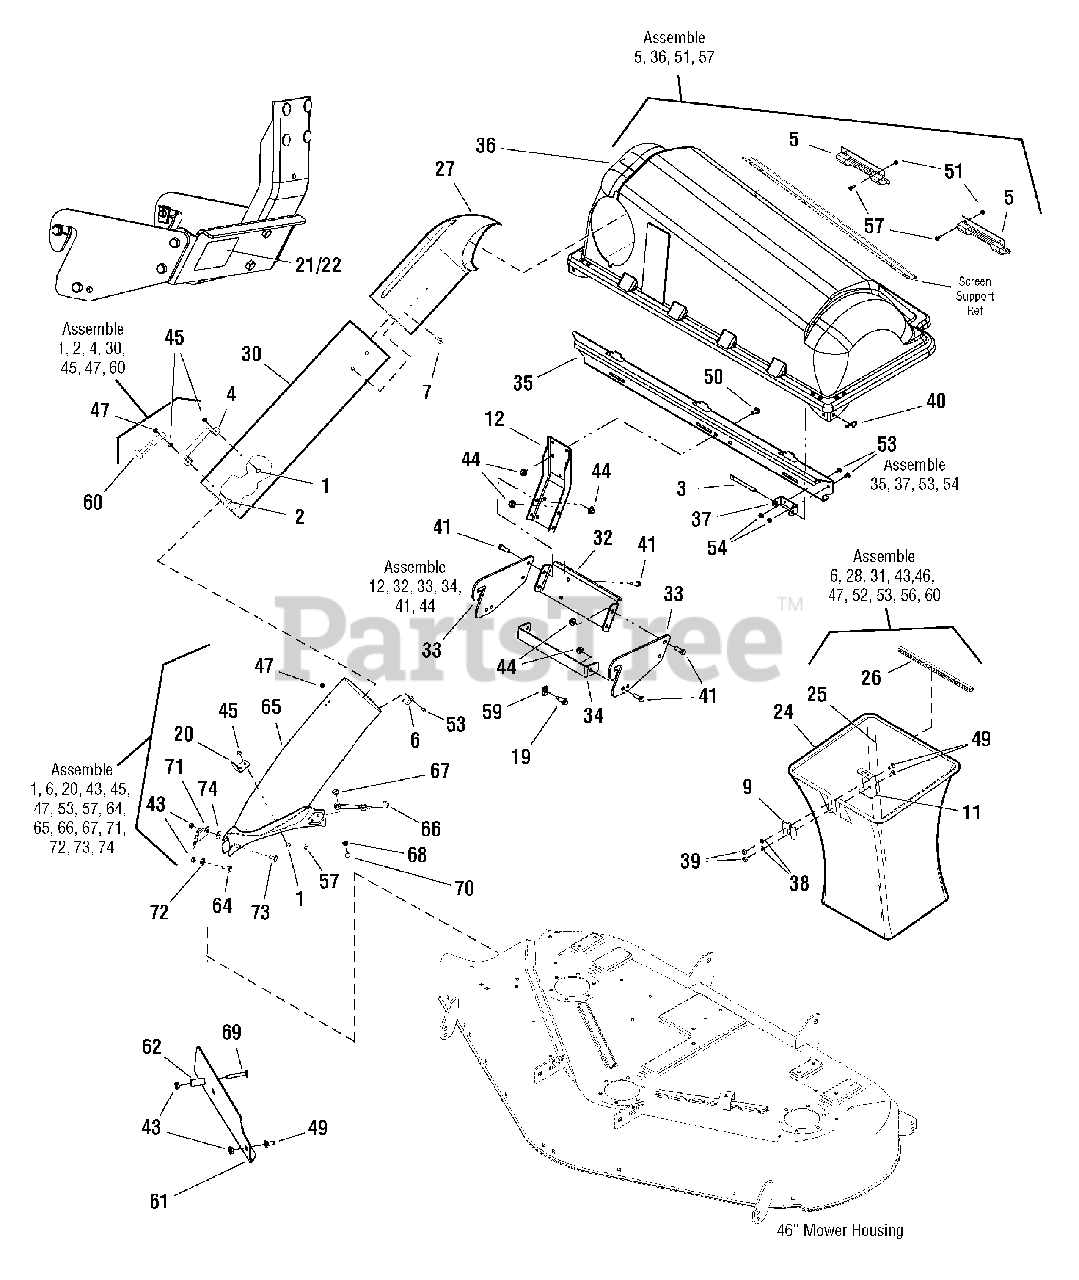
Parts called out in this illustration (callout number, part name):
1	SCREW, 1/4 - 20 x 1/2
2	SCREW, 1/4 - 20 x 1
3	PIN, Cover Hinge
4	HANDLE, Connect Tube
5	HANDLE, Plastic
6	PIN, Latch
7	SCREW, 1/4 X 3/4
9	CLAMP, Grass Bag Plain
11	HANGER, Grass Bag
12	SUPPORT, Upright
19	BOLT, Shoulder, 5/16 X 18
20	UPSTOP, Deflector
21	MYLAR OVERLAY
22	STICKER, Serial w/Bar Code
24	HOOP, Triple
25	BAG, Triple Regular
26	CLIP, Tube Grass Bag
27	ELBOW, Upper Tube Poly
30	TUBE, Clear
32	BRACKET, Upright Support
33	PLATE, Bagger Mount
34	BRACKET, Hitch Support
35	CROSS SUPPORT, Triplle bagger
36	ASSEMBLY, Cover, Triple Bagger
37	PIVOT, Hinge
38	LOCKWASHER, Spring, 5/16
39	NUT, Hex, 5/16 - 18
40	PIN, Quick
41	CAPSCREW, Hex-Head, 3/8-16 X 1-1/4"
43	NUT, Hex Whiz Lock Flange, 5/16 - 18
44	NUT, Hex-Flange, Whiz-Lock, 3/8-16
45	NUT, Hex Keps, 1/4 - 20
47	NUT, Hex Flange Top-Lock, 1/4 - 20
49	BOLT, Carriage, 5/16 - 18 x 3/4, G5
50	BOLT, Carriage, 5/16 - 18 x 3/4, G5
51	NUT, Hex Lock, 10-24 w/Nylon Insert
53	BOLT, Carriage, 1/4-20 X 5/8"
54	NUT, Hex-Flange, Whiz-Lock, 5/16 - 18
57	SCREW, Truss Head Phillips, 10 - 24 x 3/4
59	NUT, Speed, Lug-Type, 5/16-18
60	STRAP, Hood
61	BAFFLE, 46" Mower Deck
62	SPACER, 5/8" O.D., .320 Long
64	BOLT, Carriage, 5/16-18 X 1" Long
65	BOOT, Bagging
66	STRAP, Mounting Bag
67	NUT, Weld, 10-24
68	NUT, Hex, KEPS, Conical, 1/4-20
69	BOLT, Carriage, 5/16-18 X 2"
70	BOLT, Carriage, 1/4-20 X 3/4"
71	LATCH, Bagging Boot
72	SPACER, Hydraulic Lift
73	SCREW, Hex-Head, 5/16-18 X 3/4"
74	SPACER, 1" O.D.
